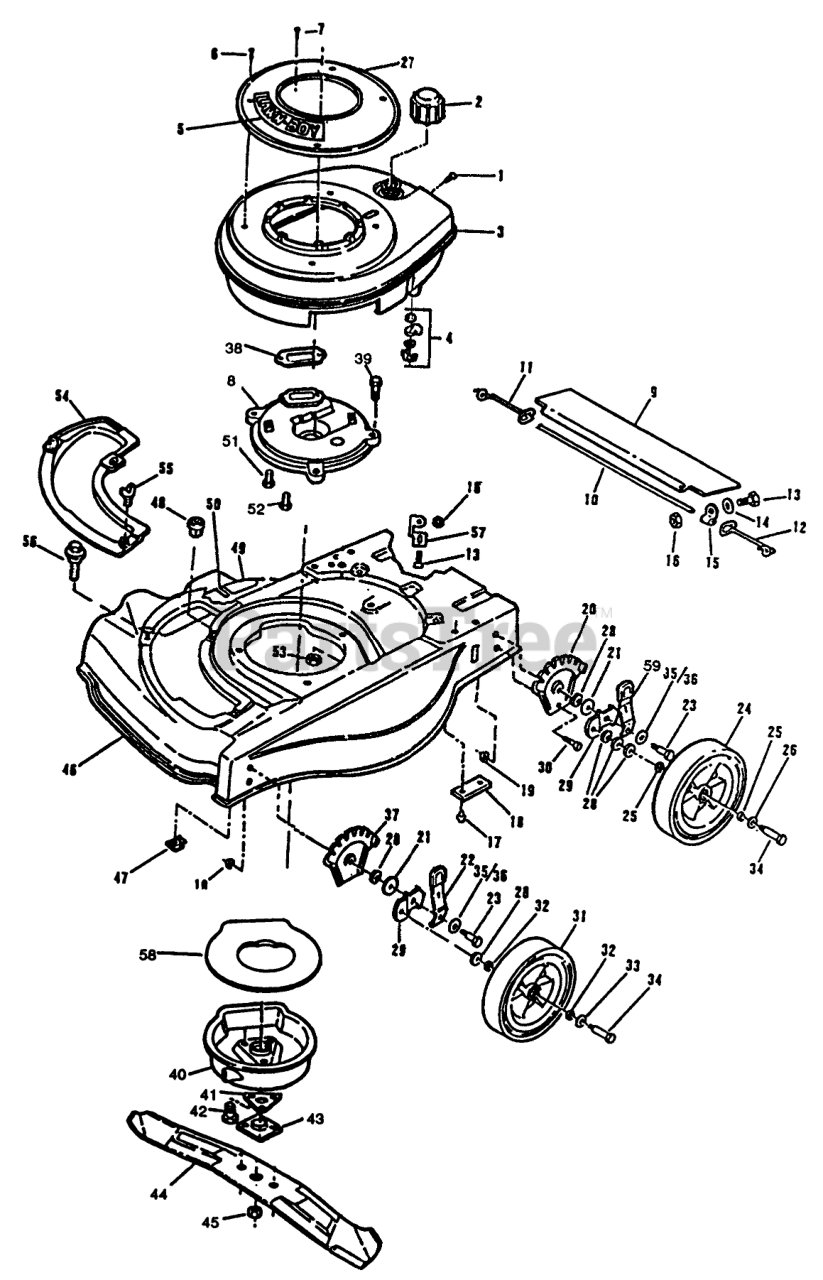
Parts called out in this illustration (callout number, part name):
1	SCREW S
2	FUEL CAP & INSERT
3	Shroud-Engine
4	SHUT OFF VALVE KIT
5	APPLIQUE
6	SCREW S
7	SCREW SEMS SM
8	PLATE,MUFFLER S
9	TRAIL/SHIELD
10	ROD T/SHIELD ADV WIRE
11	SPRING;TRAILING SHIELD RH
12	SPRIG T/SHLD ASOC
13	Screw
14	WASHER F
15	CLAMP ROD KMC
16	LOCKNUT E
17	SCREW
18	HANDLE BRKT SUP PLT LB
19	NUT
20	PLATE HGT ADJ TRO
21	WASHER
22	KNOB&SPRING FORMCO
23	BOLT
24	WHEEL&TIRE AY.
25	WASHER
26	WASHER-PLAIN
27	STARTER BASE&NUTG
28	WASHER WROUGHT
29	Bracket
30	Screw
31	Front Wheel
32	WASHER
33	WASHER-PLAIN
34	BOLT WHEEL
35	WASHER
36	WASHER
37	PLATE HGT ADJ TRO
38	Gasket
39	SCREW-HH
40	MUFFLER COVER F
41	SUPPORT F
42	SCREW
43	PLATE AND COLLAR ASM
44	21" Blade
45	NUT-BLADE
46	HSG AY-SERV 21"
47	NUT-CAGE
48	Grommet
49	Decal
50	DECAL SGI
51	SCREW F
52	SCREW V
53	NUT-LOCK F
54	CoverPlate
55	WING SCREW LAWRE
56	Bolt
57	BRACKET ARGO
58	BAFFLE,MUFFLER S
59	KNOB&SPRING AY FORMCO
